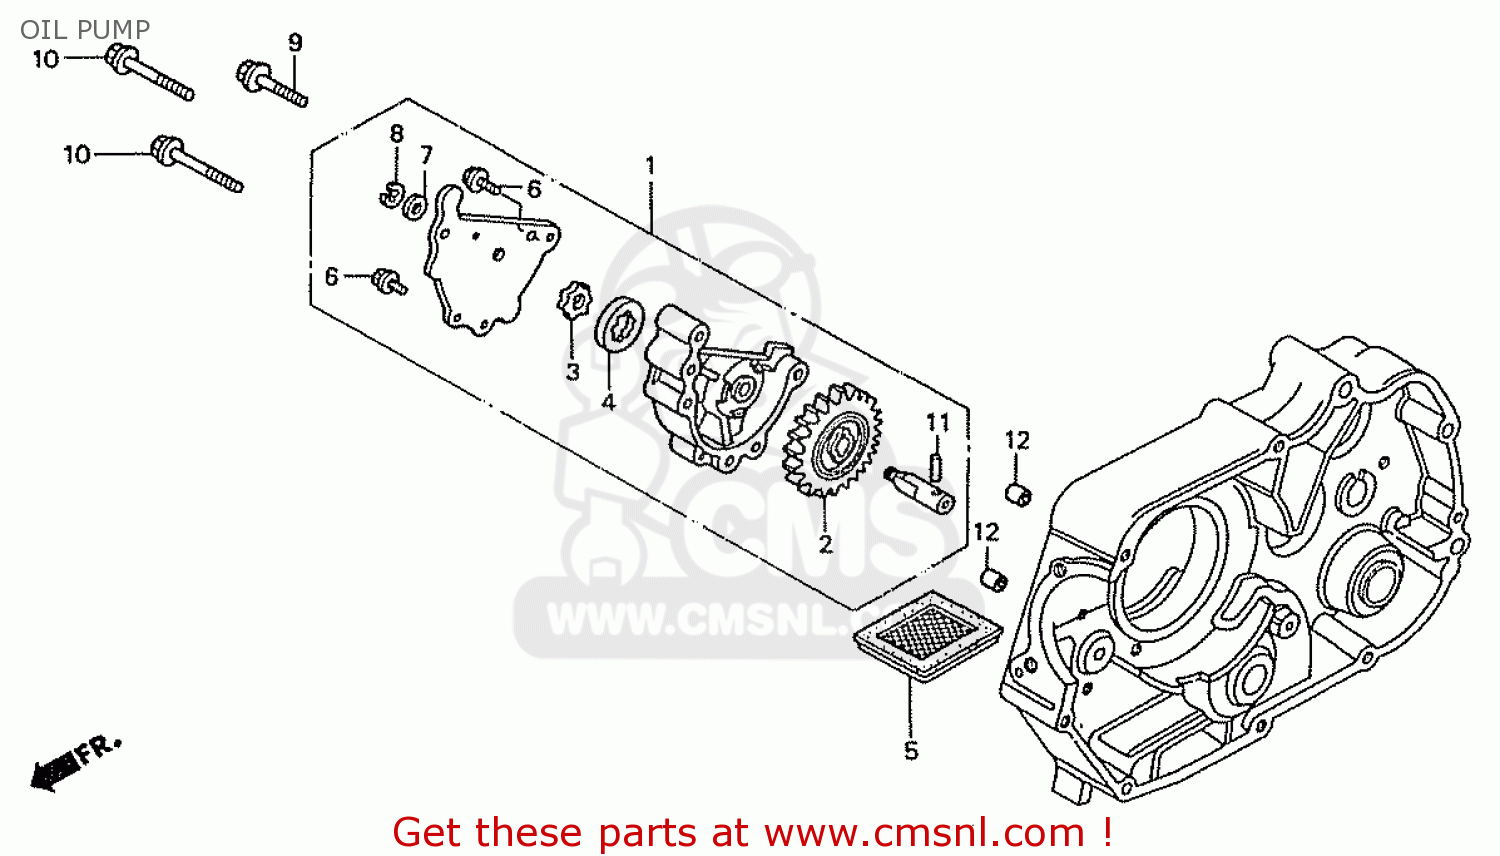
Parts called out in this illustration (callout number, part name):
1	OIL PUMP ASSY
2	GEAR,OIL PUMP DRI
3	ROTOR, OIL PUMP INNE
4	ROTOR OIL PUMP OU
5	SCREEN, FILTER
6	BOLT,FLANGE,5X10
7	WASHER,THRUST
8	E RING,5
9	BOLT,FLNAGE,6X35
10	BOLT,FLANGE,6X40
11	ROLLER,3X15.8
12	PIN,DOWEL 8X12
